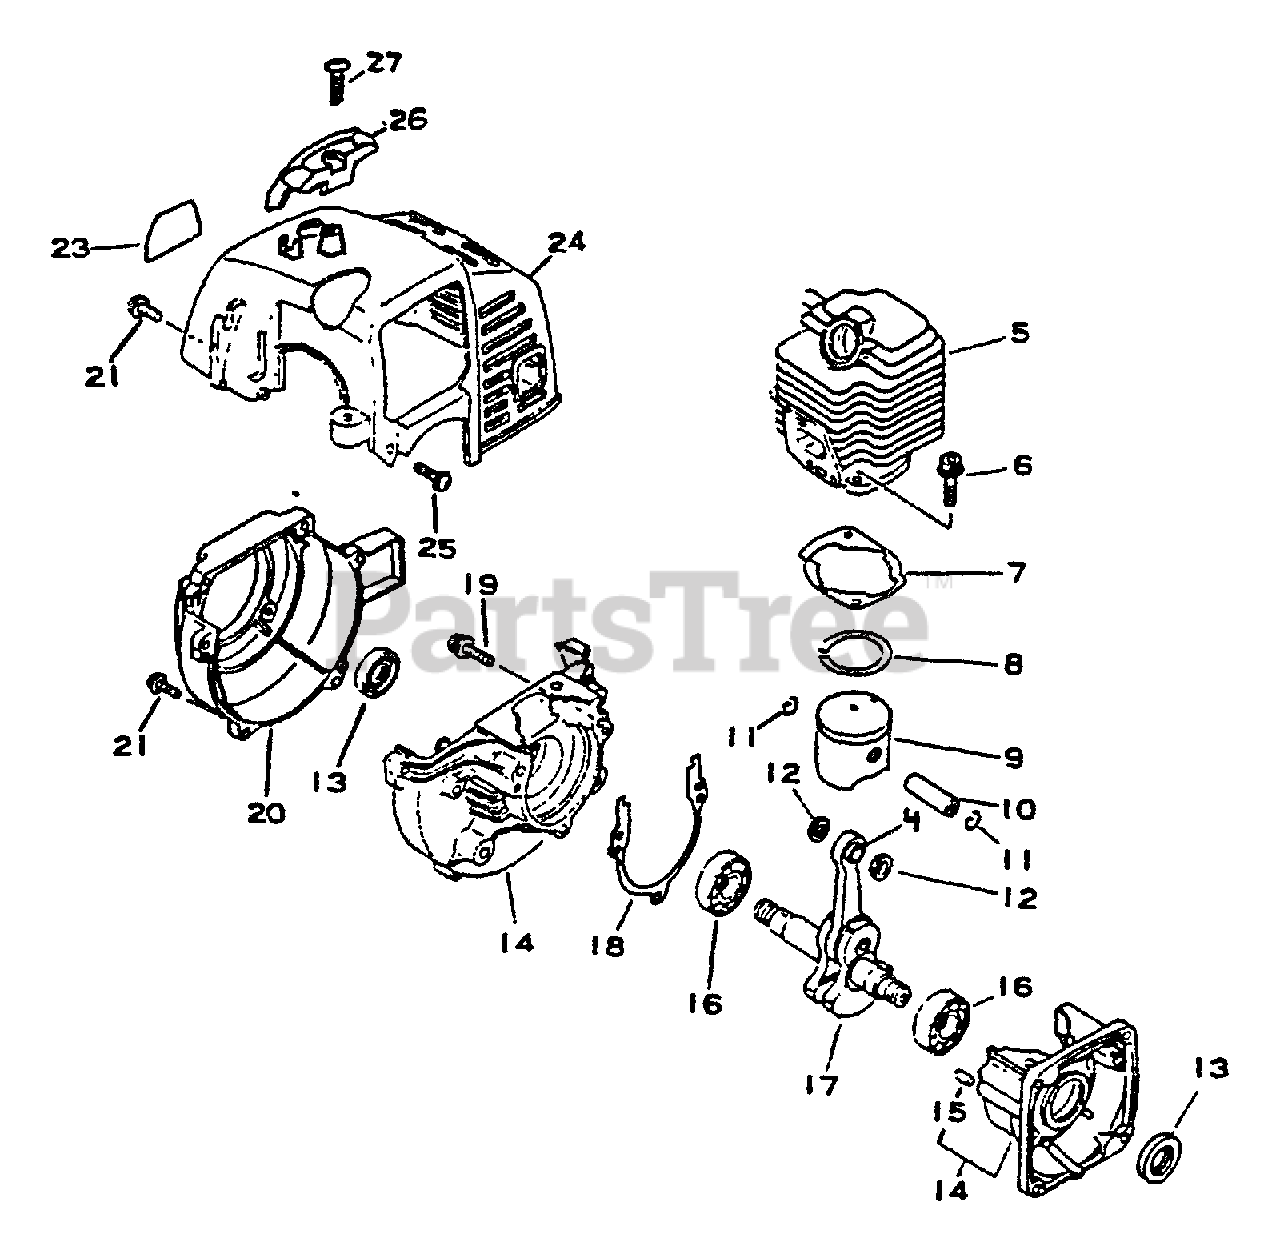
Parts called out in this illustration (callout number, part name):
4	BEARING, NEEDLE
5	CYLINDER
6	BOLT 5×22
7	GASKET, CYLINDER
8	RING, PISTON
9	PISTON
10	PIN, PISTON 8
11	RING, SNAP
12	WASHER, THRUST
13	SEAL, OIL 12
14	CRANKCASE KIT
15	PIN, LOCATING 4
16	BEARING, BALL - 6201 C3
17	CRANKSHAFT ASSY
18	GASKET, CRANKCASE
19	SCREW 5×28
20	COVER, FAN - ORANGE
21	SCREW 4×16
23	LABEL - MODEL 2310
24	COVER, ENGINE
25	SCREW 4×12
26	GUARD, TOP - BLACK
27	SCREW 5×16
